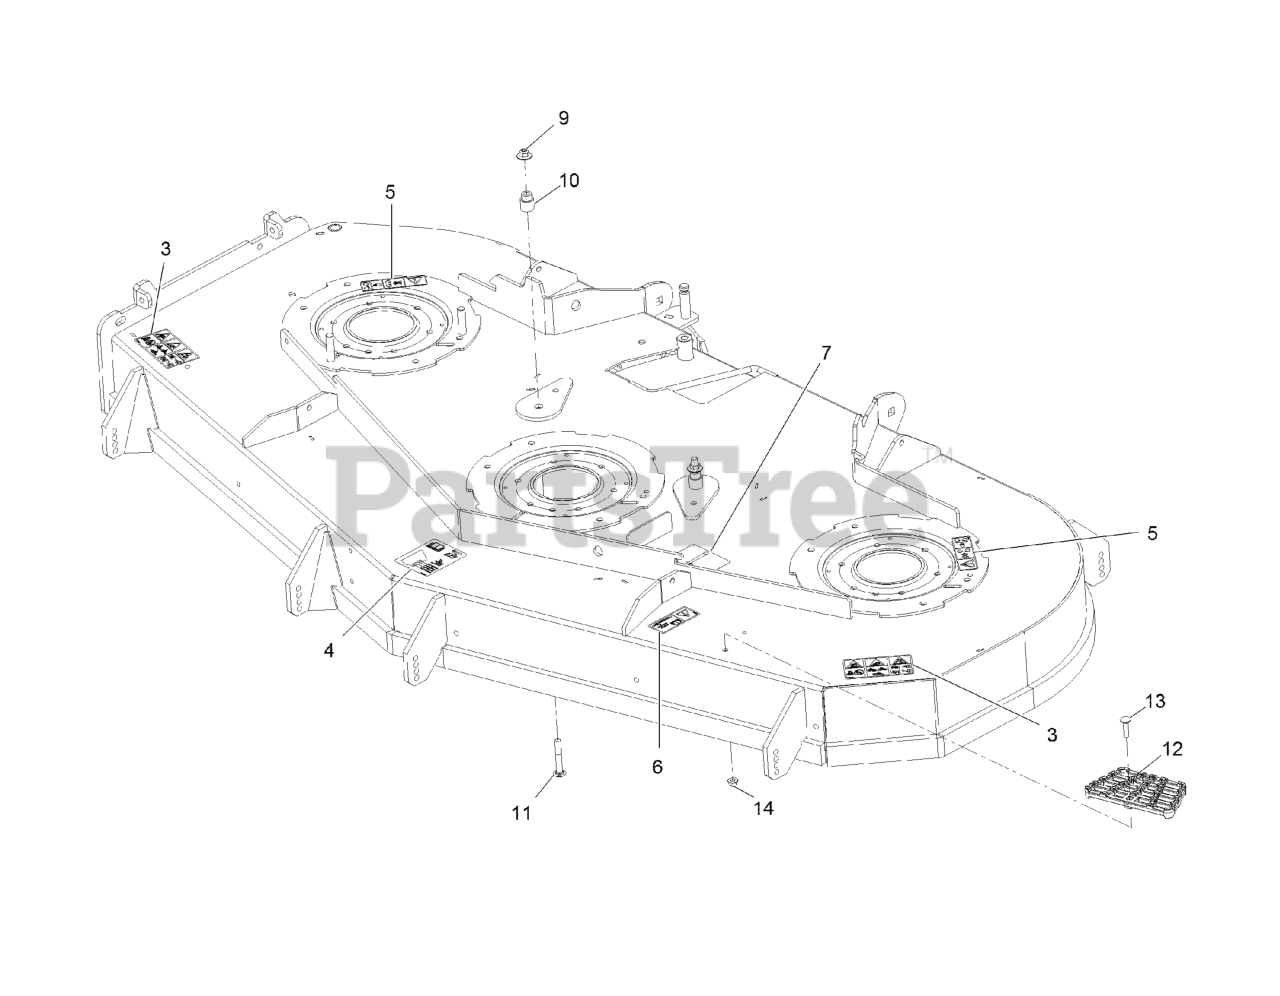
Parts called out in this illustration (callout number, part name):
3	DECAL-DANGER THROWN OBJECTS
4	DECAL-ROLLER, ANTI-SCALP
5	DECAL-COVER, MISSING
6	DECAL-TORQUE, BOLT
7	DECAL-BELT ROUTING
9	Nut-Nyloc 3/8-16 Flg
10	BUSHING-IDLER
11	SCREW-CARR
12	STEP-DECK
13	Bolt-Carriage 5/16-18 X 1 1/4
14	NUT-HF, NI
